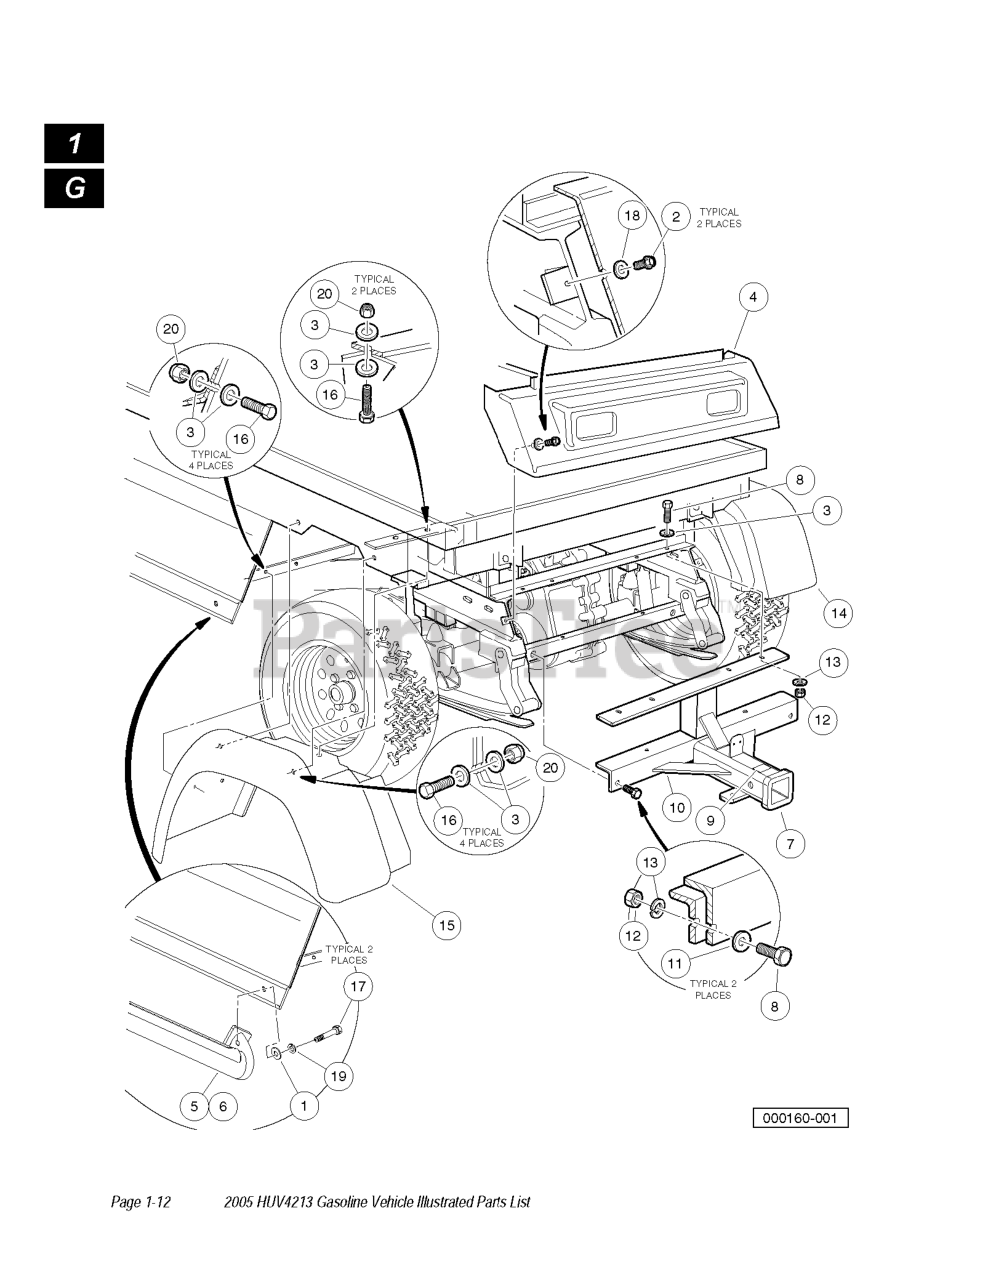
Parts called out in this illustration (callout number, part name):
1	WASHER, 3/8 FLAT
2	SCREW HX TYP TT
4	TAIL SKIRT, CAI
5	SIDE STEP BAR
6	SIDE STEP BAR
7	KIT, REAR RECEIVER
8	SCREW HEX CAP
9	DECAL, TRAILER HITCH
10	RECEIVER HITCH WELD ASM
11	WASHER, 5/16 TYPE A FLAT
12	NUT, 5/16-18 HEX
13	LOCKWASHER, 5/16 SPLIT
14	FENDER, RIGHT REAR
15	FENDER, LEFT REAR
17	SCREW, CAP, HEX HD 3/8-16X1.00
18	WASHER 1/4 FLAT
19	WASHER,LOCK,HEL SP 3/8 REG
20	LOCKNUT, 1/4-20 NYLON INSERT
